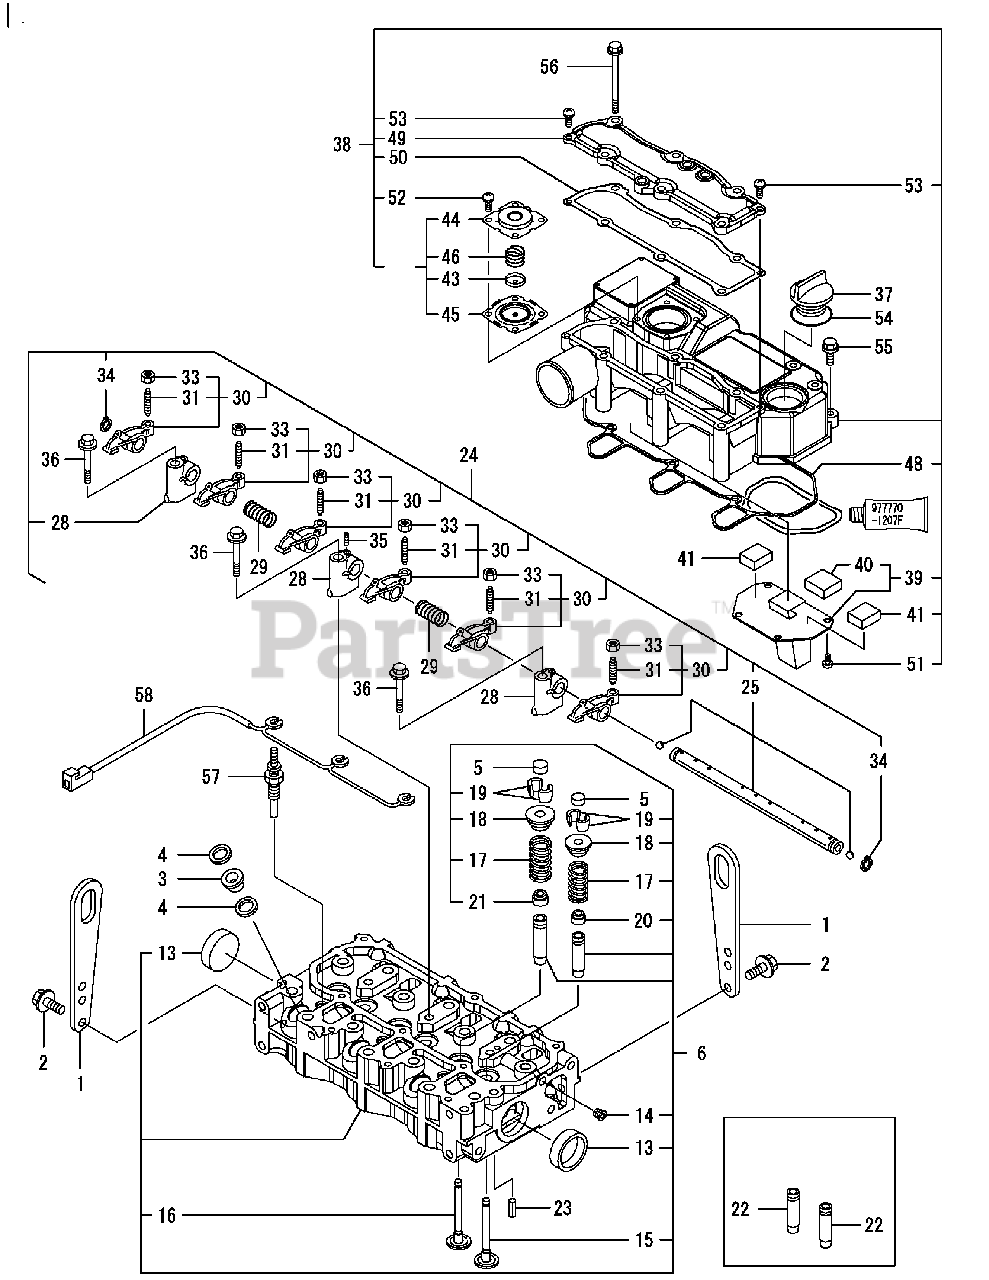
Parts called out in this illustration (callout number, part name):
1	Lifter, Engine
2	Bolt, M 8 x 16 Plated
3	Protector, Nozzle
4	Gasket, Nozzle
6	Head Assembly, Cylinder
14	Plug Pt, 1/16, Screw
16	Valve, Exhaust
18	Retainer, Spring
20	Seal, Valve Stem
21	Seal, Valve Stem
23	Spring Pin, 6 x 12
24	Support Assembly, Arm
25	Shaft Assembly, Rocker
28	Support, Rocker Arm
30	Arm Assembly, Rocker
33	Nut, M8 x P1.0
35	Screw, M 5 x 16
36	Bolt, M8 x 40 Plated
38	Bonnet Assembly, Head
40	Baffle, Breather
41	Baffle, Breather
43	Plate, Diaphragm
44	Cover, Diaphragm
46	Spring, Diaphragm
48	Gasket, Bonnet
50	Gasket, Bonnet Cover
51	Screw, 5 x 10, Tapping
52	Screw, 5 x 10, Tapping
54	O-Ring, 1A P-32.0
55	Bolt, M 6 x 20 Plated
56	Bolt, M 6 x 75 Plated
57	Plug, Glow
58	Connector, Glow Plug
